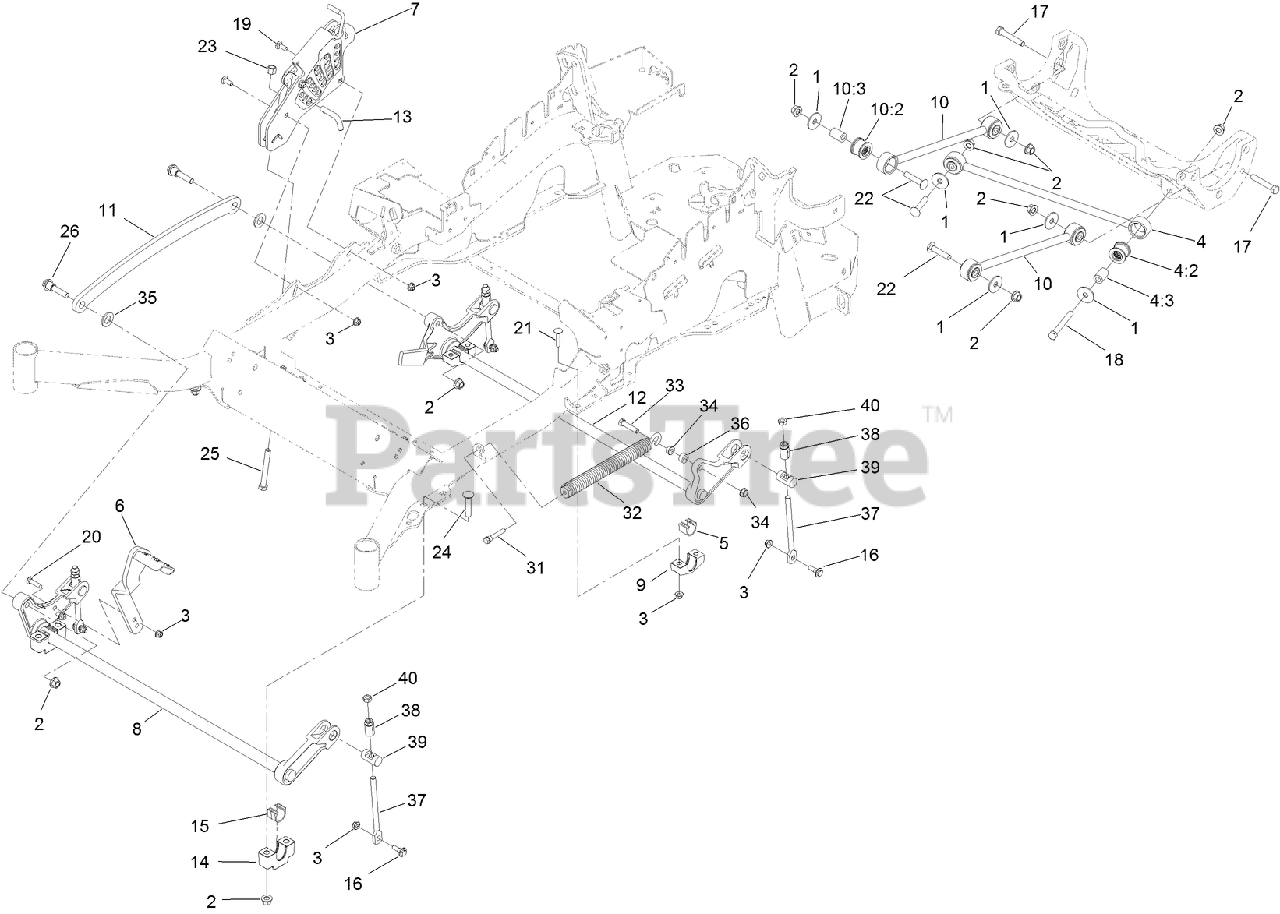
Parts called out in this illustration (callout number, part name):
1	WASHER-THRUST
2	NUT-LOCK
3	NUT-HF, NI
4	PANHARD ROD ASM
4:2	BUSHING-SUSPENSION, RUBBER
4:3	SPACER
5	BEARING-CROSS SHAFT, REAR
6	LEVER-FOOT
7	HOC ASM
8	DECK LIFT-FRONT
9	SUPPORT-CROSS SHAFT, REAR BEARING
10	DECK STRUT ASM
10:2	BUSHING-SUSPENSION, RUBBER
10:3	SPACER
11	LINK-LIFT, DECK
12	LIFT-DECK, REAR
13	PIN-HOC
14	SUPPORT-CROSS SHAFT, BEARING
15	BEARING-CROSS SHAFT, FRONT
16	SCREW-SHOULDER, HHF
17	SCREW-HH
18	SCREW-HH
19	BOLT-CARR
20	SCREW-CARR
21	SCREW-CARR
22	SCREW-CARR
23	NUT-LOCK, NI
24	BOLT-CARR
25	BOLT-TAP
26	SCREW-HHF, SHOULDER
31	BOLT-SHOULDER
32	SPRING-EXTENSION
33	SCREW-HH
34	NUT-HF
35	WASHER-FLAT
36	SPACER
37	LINK-ADJUSTER, DECK LIFT
38	ADJUSTER-LIFT, DECK
39	TRUNNION
40	NUT-JAM
